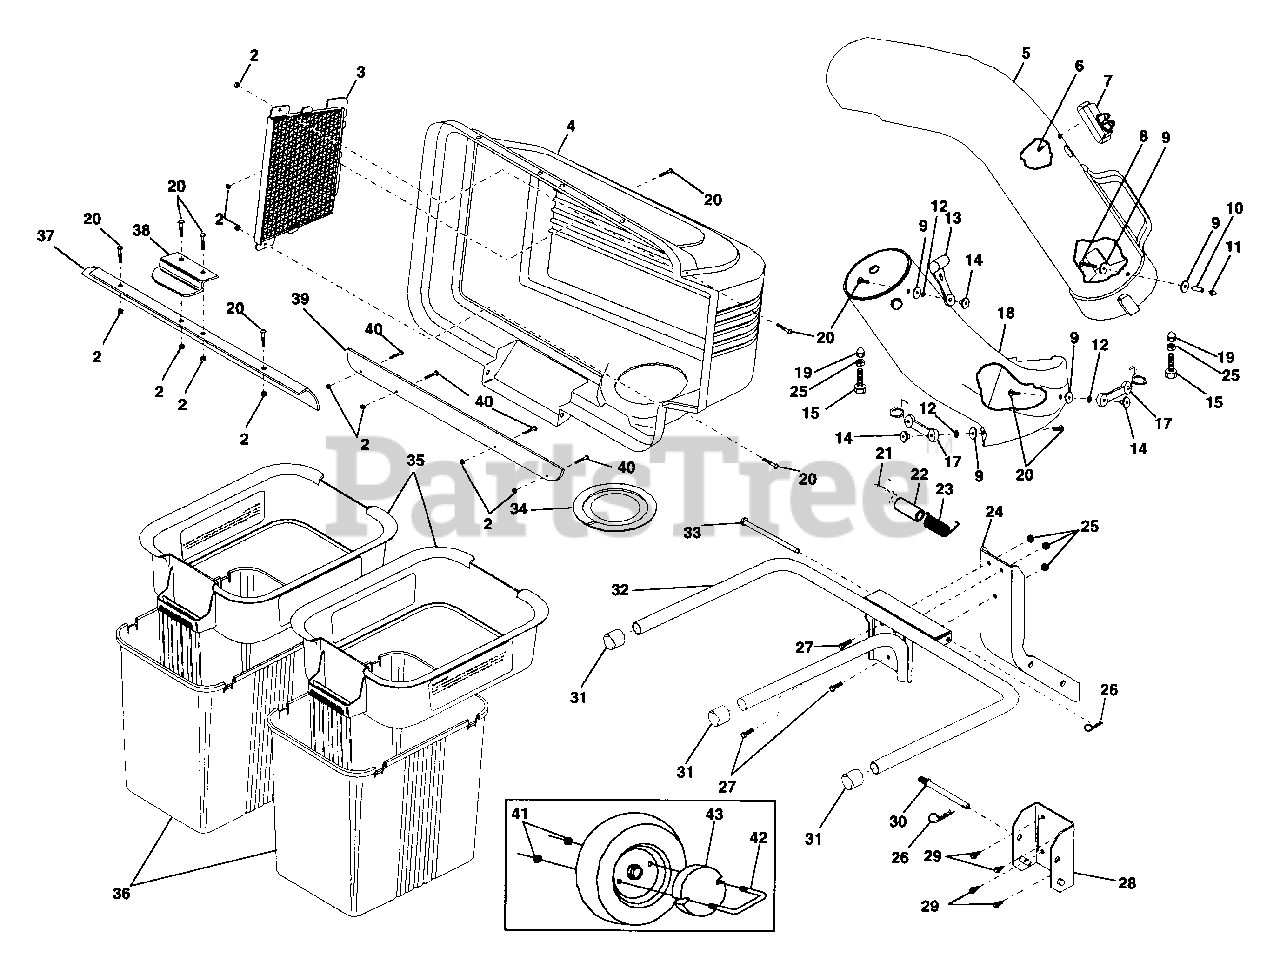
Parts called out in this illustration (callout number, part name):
2	Locknut #10-24
3	Screen, Cover
4	Cover
5	Chute, Upper
6	Screw, Special
7	Indicator, Dump Bag
8	Screw, #10-24 x 1-1/8
9	Washer 3/16 x 3/4 x 16 Ga.
10	Spacer, Split
11	Nut, Acorn #10-24
12	Washer, lock
13	Latch, Chute
14	Nut, Weld
15	Bolt, Hex 5/16-18 x 1
17	Latch Assy., Bagger
18	Chute, Lower
19	Nut, Acorn 5/16-18
20	Screw #10-24 x 5/8
21	Spring, Cover L.H. (black)
22	Spacer, Cover
23	Spring, Cover R.H. (gray)
24	Post, Support
25	Locknut 5/16 x 18
26	Spring, Retainer
27	Bolt, Hex 5/16-18 x 3/4
28	Bracket, Mounting
29	Screw, Thread Rolling 5/16-18 x 1/2
30	Pin, Support Post
31	Cap, Tubing End
32	Bagger, Frame
33	Pin, Hinge
34	Gasket, Cover
35	Container, Top
36	Container, Bottom
37	Seal, Cover
38	Latch Handle, Cover
39	Strip, Seal
40	Screw #10-24 x 1/2
41	Locknut 3/8-16
43	Weight, Wheel
